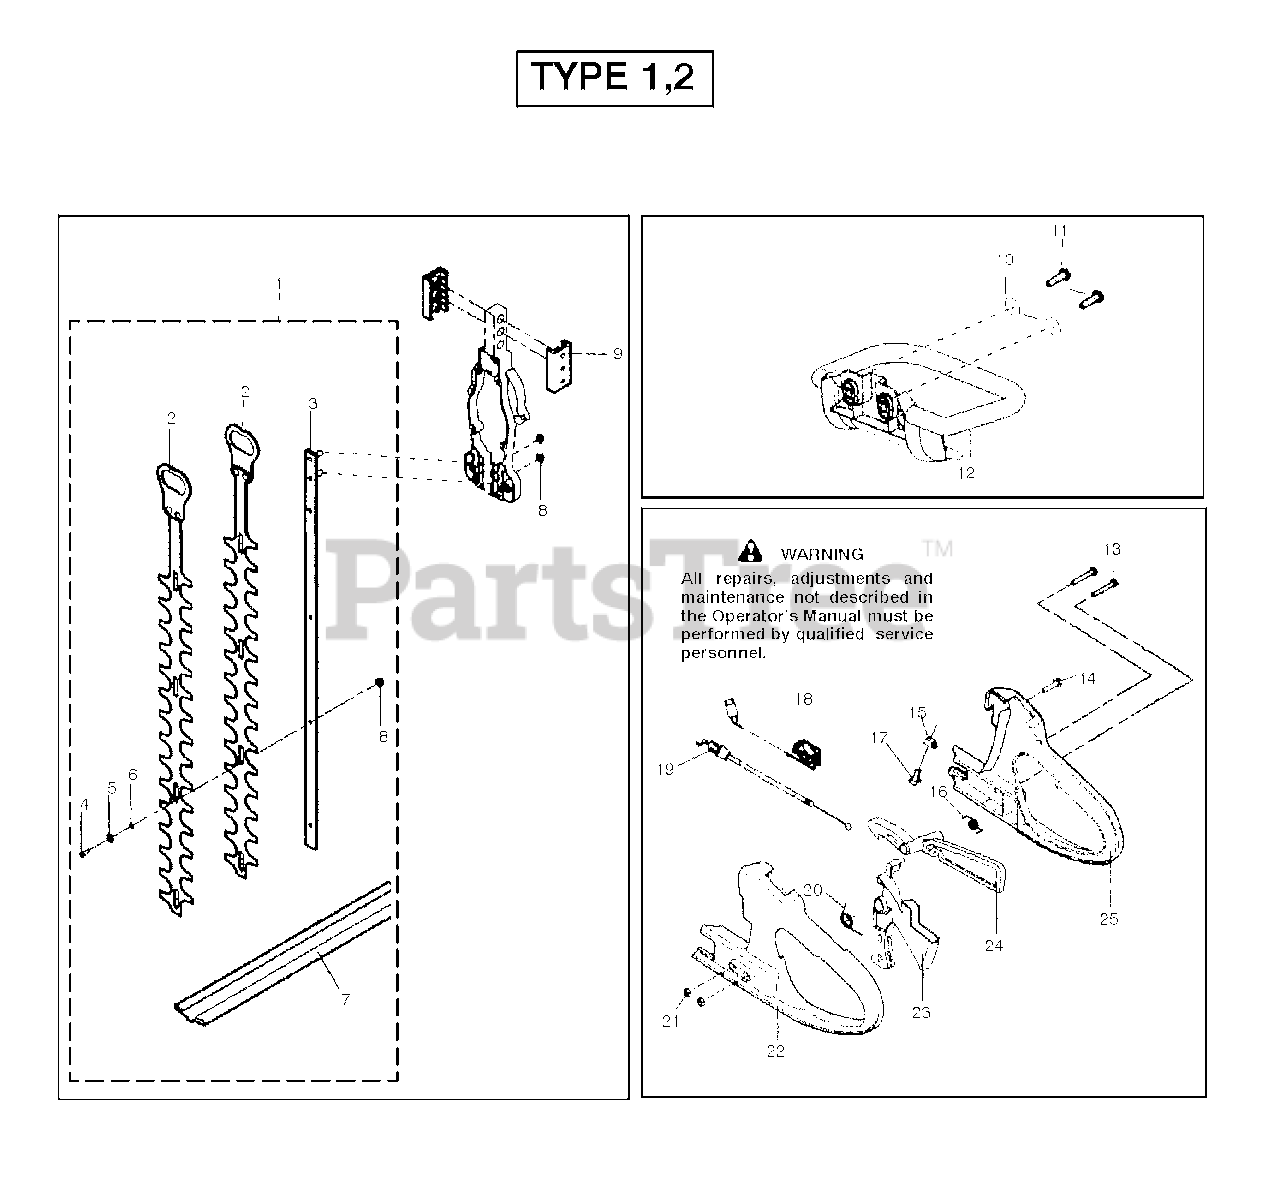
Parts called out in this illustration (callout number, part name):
1	BLADE KIT ASSY
5	CONICAL SPRING WASHER KAAZ
6	CUTTER WASHER KAAZ
8	U-HEXAGON NUT FLANGE KAAZ
11	SCREW-10-24X1-3/8-TAPTI
13	SCREW SOCKET KAAZ
14	SCREW TAPPING KAAZ
16	SPRING KAAZ
18	STOP SWITCH ASSY KAAZ
20	SPRING KAAZ
21	U-HEX NUT KAAZ
